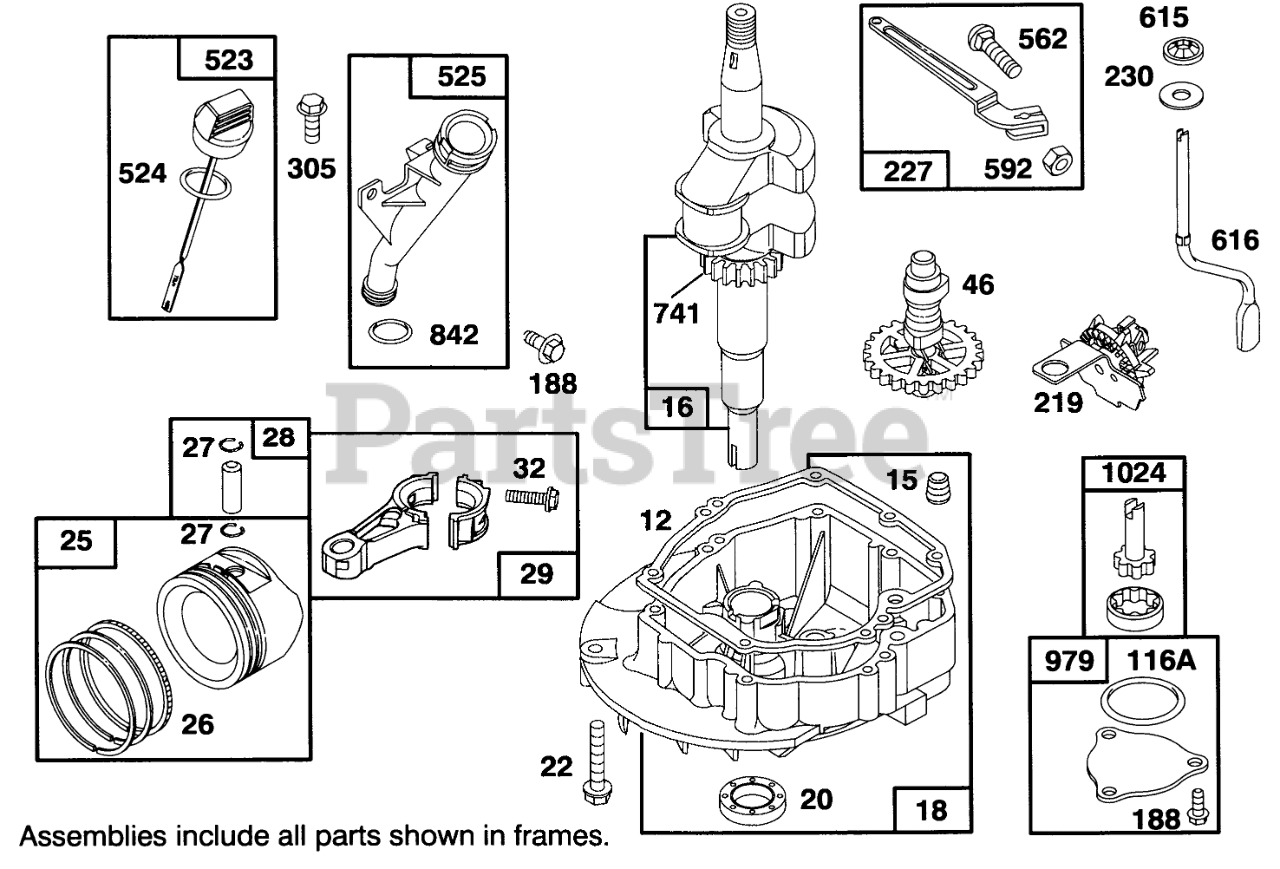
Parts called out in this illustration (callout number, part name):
12	ENGINE BASE GASKET
15	PIPE PLUG
16	Crankshaft
18	ENGINE SUMP
20	SEAL-OIL
22	SCREW - ENGINE BASE
25	STD PISTON ASSEMBLY
26	STD RING SET
27	PISTON PIN LOCK
28	PIN ASM - PISTON
29	CONNECTING ROD
32	SCREW - CONNECTING ROD
46	CAM GEAR
116A	O RING SEAL
188	Screw-Cap
219	GOVERNOR/OIL SLINGER
227	GOVERNOR LEVER ASSEMBLY
230	WASHER
305	SCREW - HEX HEAD
523	DIPSTICK-OIL
524	O-RING
525	OIL FILLER TUBE
562	GOVERNOR LEVER BOLT
592	HEX NUT
615	FASTENER
616	GOVERNOR CRANK
741	TIMING GEAR
842	O-RING
979	OIL PUMP COVER
1024	OIL PUMP
